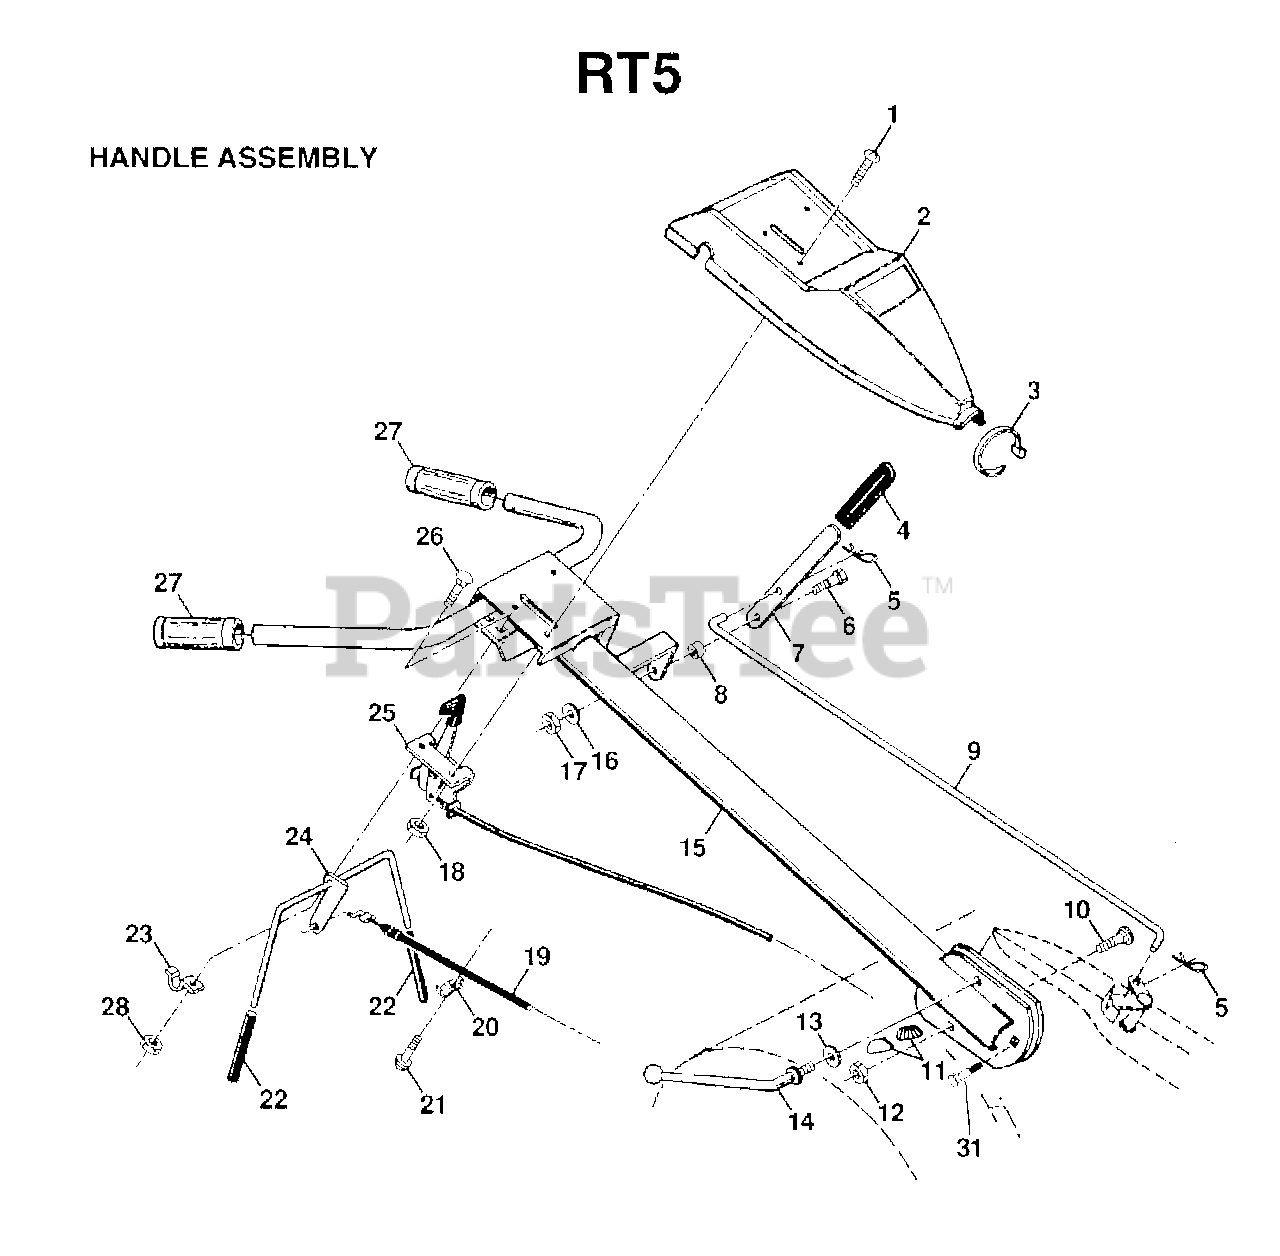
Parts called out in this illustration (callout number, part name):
1	SCREW.PNHD.10-24
3	TIE CABLE CRT
4	RETAINER M
5	RETAINER M
6	SHOULDER BOLT ST
7	SHIFT HANDLE CRT
8	GROMMET.RUBBER.CRT.TILLER
9	SHIFT ROD CRT
12	LOCKNUT
13	WASHER CRT
16	LOCKWASHER
17	NUT
18	NUT **
19	CABLE, CLUTCH 48 "Z"
20	CONDUIT CLIP T
21	TAPPING SCREW
22	GRIP BAR CRT(1)
23	CLAMP.BAR.CRT.BLACK
24	BAR ASSY CONTROL
25	CONT,THROTTLE
27	GRIPS (2EACH)
28	NUT
31	BOLT.PIVOT
